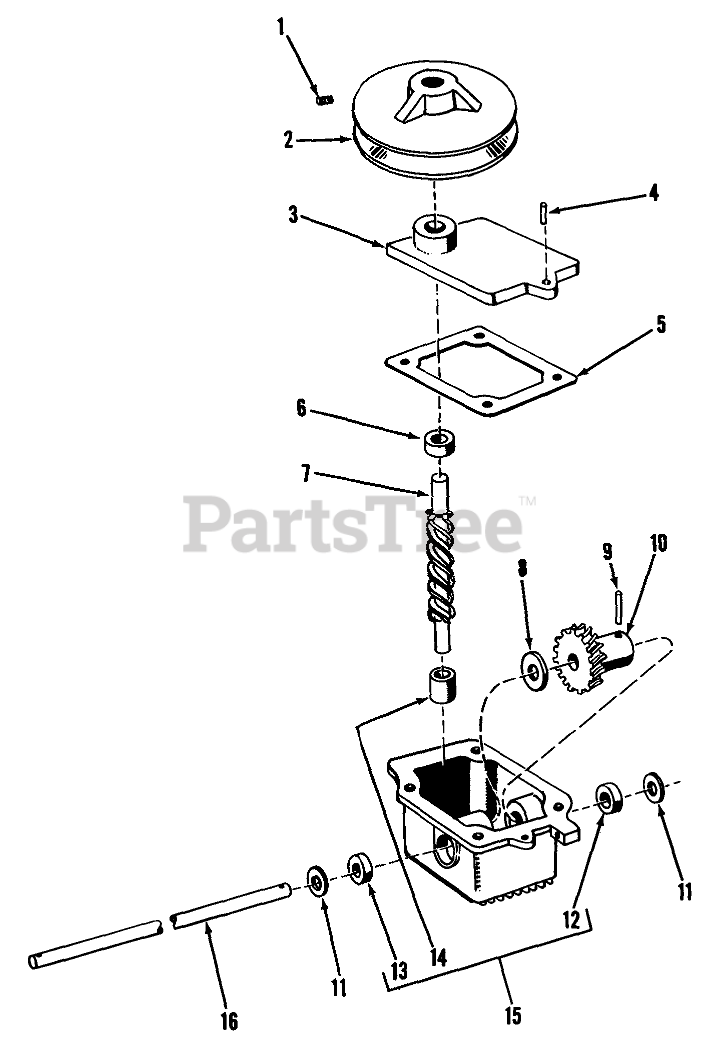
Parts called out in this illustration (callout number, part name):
1	SCREW-HSH
2	Pulley Gear Box
3	Cover Gear Box
4	3/16 X 1/2 ROLL PIN
5	GASKET
6	Bearing
7	Worm Shaft
8	THRUST WASHER
9	5/32 X 7/8 ROLL PIN
10	WORM GEAR
11	Seal
12	Bushing
13	Bushing
14	.437 NEEDLE BEARING
15	Gear Case
16	Shaft, Transmission 25"
